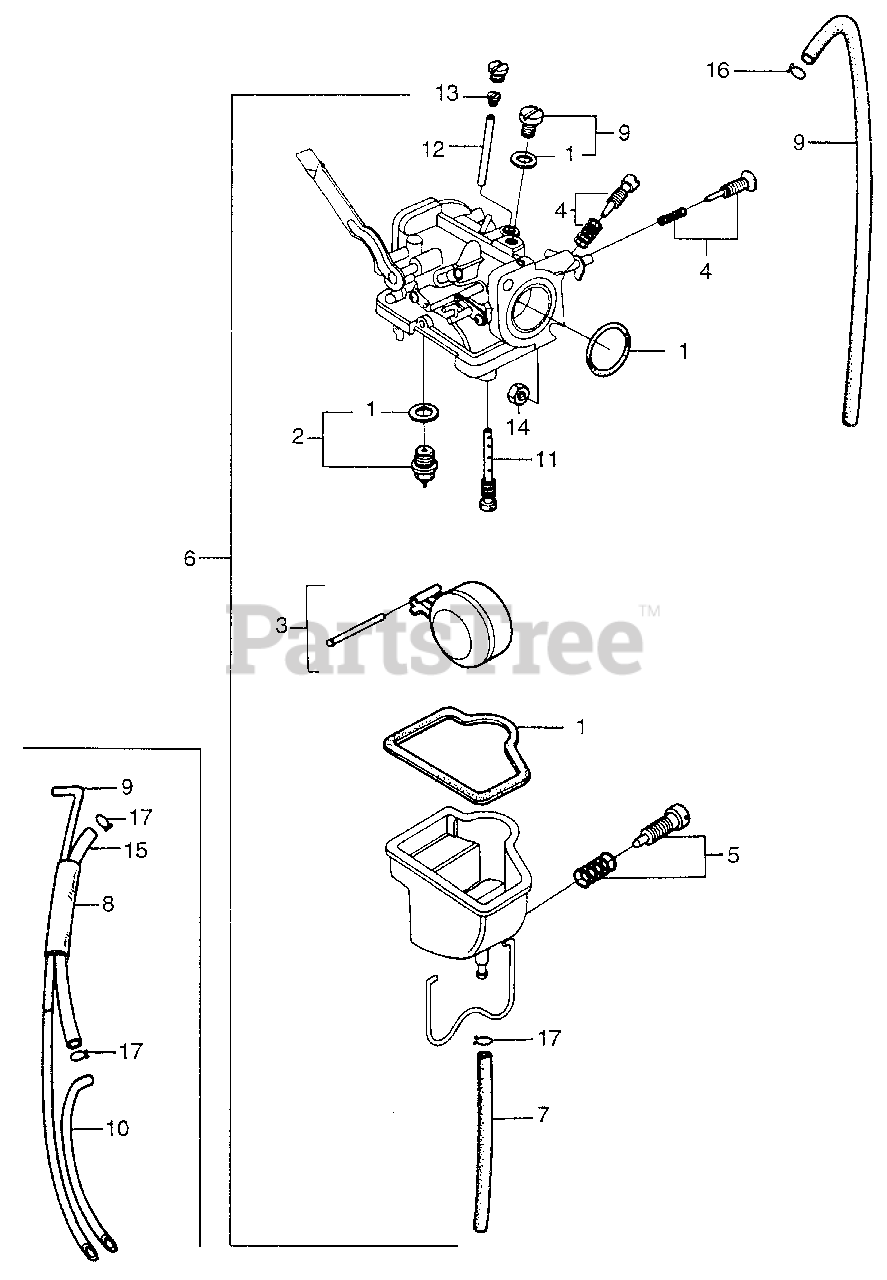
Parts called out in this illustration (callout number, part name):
1	GASKET SET (NOT AVAILABLE)
2	VALVE SET, FLOAT
4	SCREW SET A (NOT AVAILABLE)
5	SCREW SET, DRAIN (NOT AVAILABLE)
6	CARBURETOR ASSY. (NOT AVAILABLE)
7	PIPE, RUBBER (2.5X7X60) (NOT AVAILABLE)
8	RUBBER, SUPPORTER
9	TUBE, VALVE BREATHER (NOT AVAILABLE)
10	TUBE, CARBURETOR OVERFLOW (NOT AVAILABLE)
11	JET, MAIN (#55) Use up to Engine SN 1205100.
11	JET, MAIN (#58) Use up to Engine SN 1205100.
11	JET, MAIN (#58) Use from Engine SN 1205101 to 2000000.
11	JET, MAIN (#58) Use from Engine SN 2000001.
11	JET, MAIN (#60)
11	JET, MAIN (#62) Use up to Engine SN 1205100.
12	JET, SLOW (#42)
12	JET, SLOW (#38)
12	JET, SLOW (#40)
12	JET, SLOW (#45)
12	JET, SLOW (#48)
13	JET, SLOW AIR
13	JET, PILOT (#38)
13	JET, PILOT (#40)
13	JET, PILOT (#48)
13	JET, PILOT (#42)
13	JET, PILOT (#45)
14	NUT, HEX. (5MM)
15	TUBE (4.5X130)
15	BULK HOSE, FUEL (4.5X3000) (4.5)
15	BULK HOSE, FUEL (4.5X3000) (4.5X132)
16	CLIP, TUBE (B6.5)
17	CLIP, TUBE (4.5)
